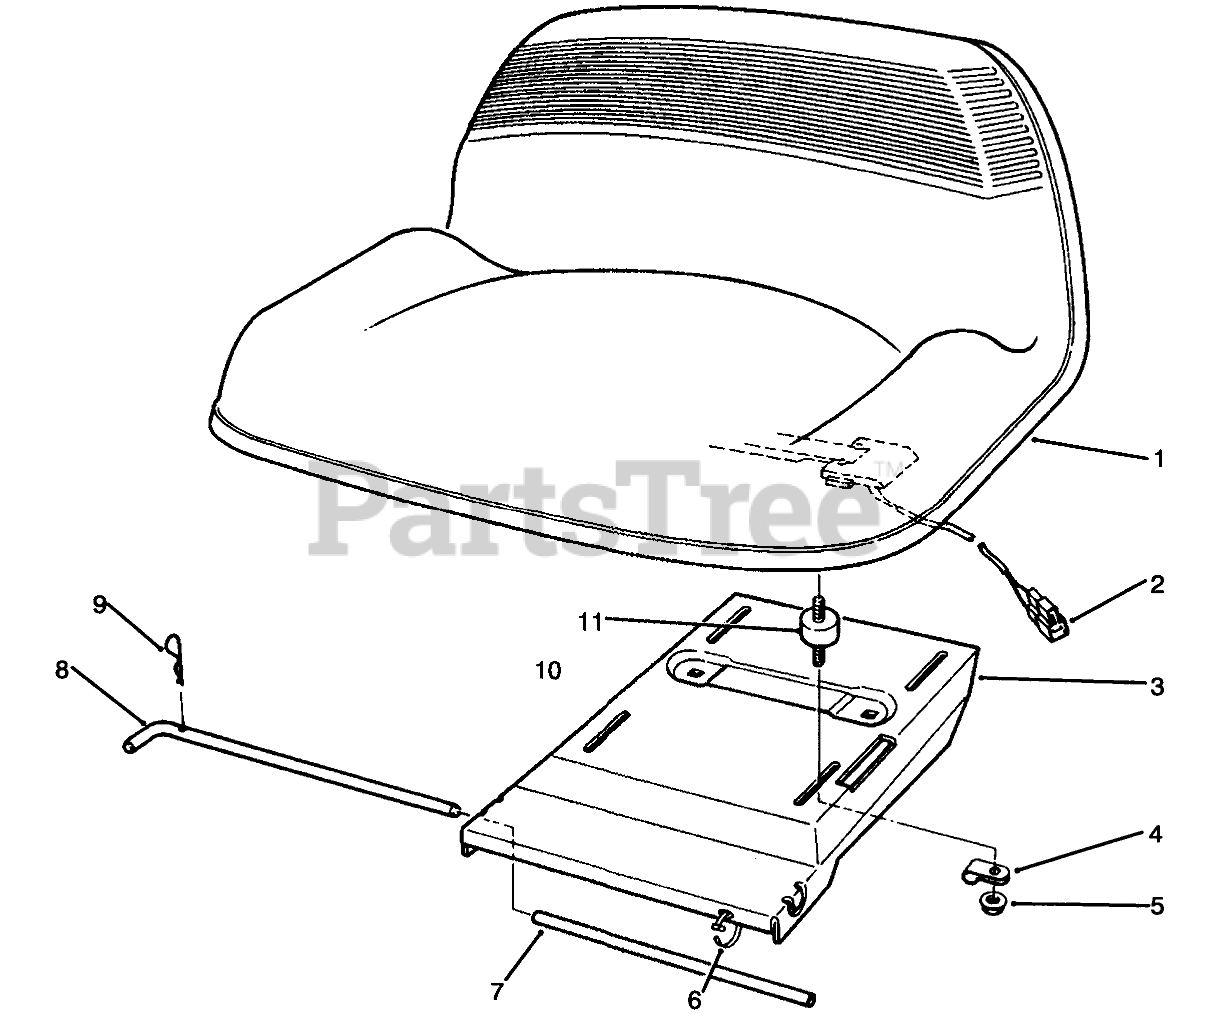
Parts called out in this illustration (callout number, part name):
1	SEAT
2	SWITCH-SEAT
3	Base-Seat
4	CLAMP
5	NUT-HF
6	TIE-CABLE
7	TUBE-SEAT
8	ROD-SEAT BASE
9	PIN-COTTER
11	ISOLATER-SEAT
